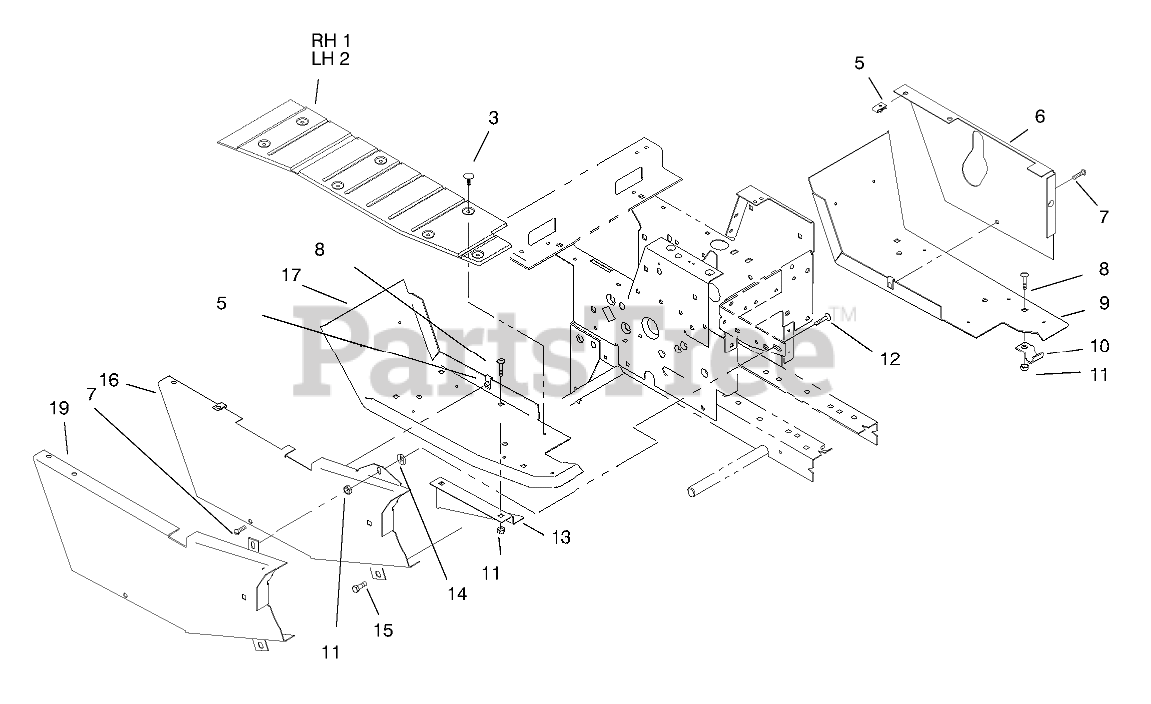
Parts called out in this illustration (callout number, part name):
1	PAD-FOOT RH
2	PAD-FOOT LH
3	FASTENER-PANEL
6	COVER-LH
7	SCREW-PPH
8	BOLT-CARR
9	FOOTREST-LH
10	BRACKET
11	NUT-LOCK, NI
12	BOLT-CARR
13	GUIDE-LOWER BELT
14	NUT-PUSH
15	Bolt
16	GUARD WA - BELT (RED)
17	FOOTREST-RH
